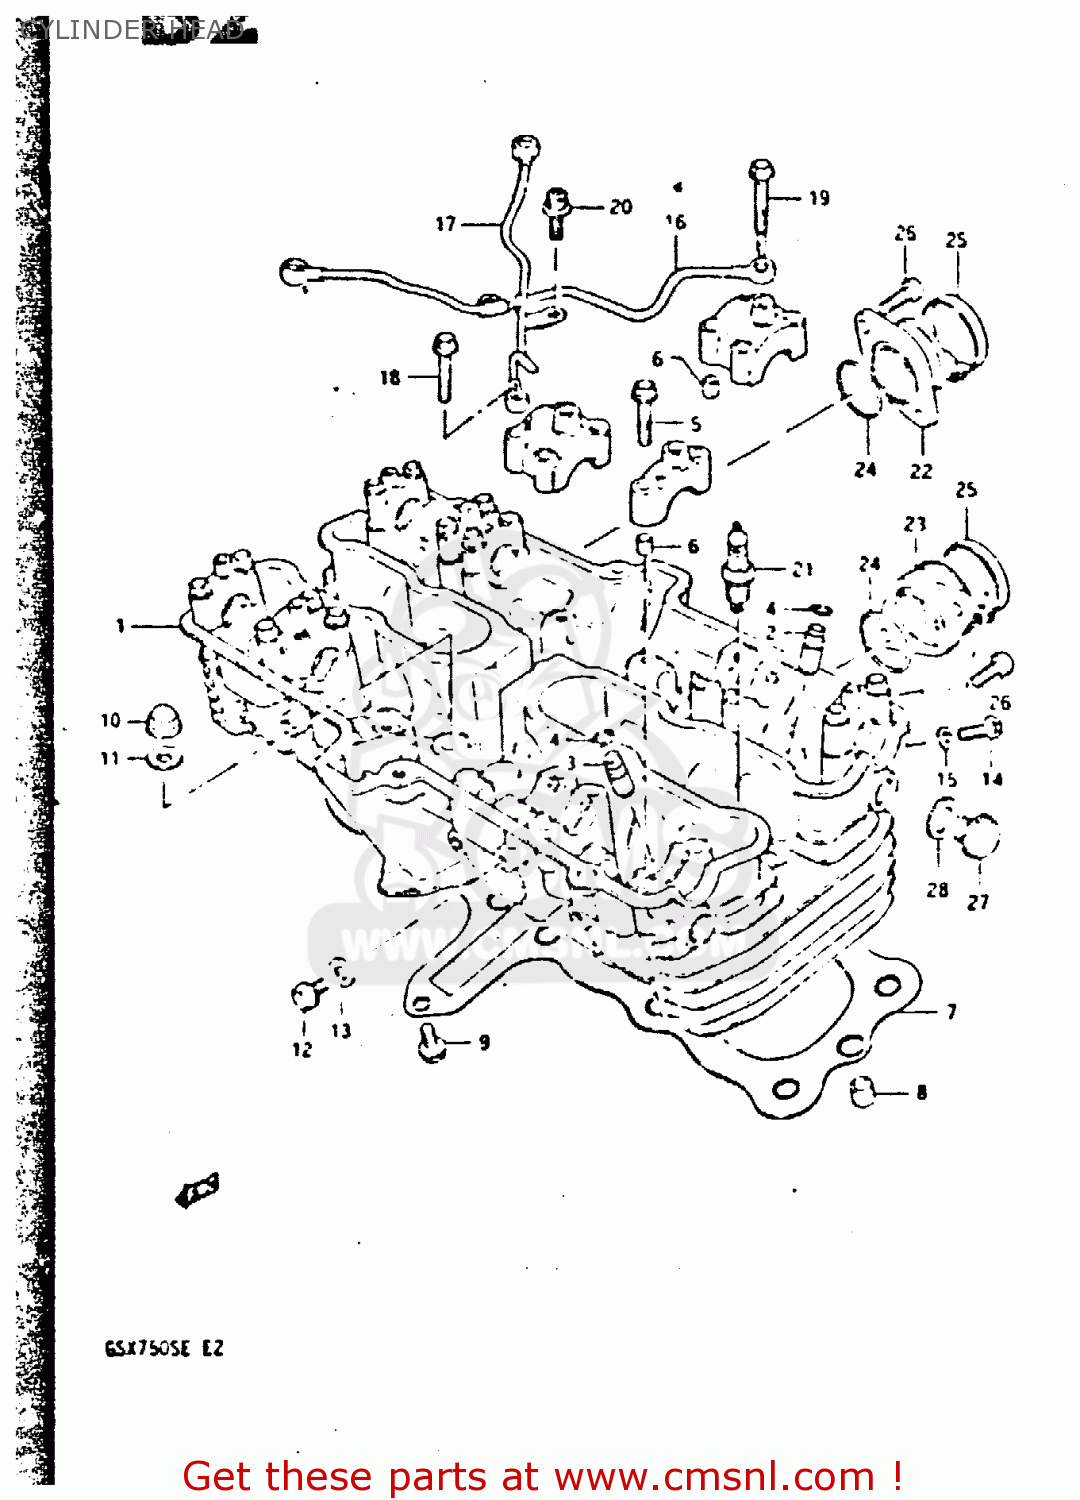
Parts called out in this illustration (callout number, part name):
1	CYLINDER HEAD SET
2	GUIDE,INTAKE VALVE
3	GUIDE,INTAKE VALVE
4	RING,SNAP
5	BOLT(6X39)
6	PIN(6.2X8X11)
7	GASKET,CYLINDER HEAD (NAS)
8	PIN
9	BOLT
10	NUT
11	GASKET(10.5X22X2) (NAS)
12	BOLT
13	GASKET(6.2X13X1.2) (NAS)
14	SCREW
15	GASKET(5.3X9.3X1.2) (NAS)
16	PIPE,OIL CYLINDER HEAD NO.1
17	PIPE,OIL CYLINDER HEAD
18	UNION
19	BOLT,UNION
20	BOLT
21	SPARK PLUG D8EA
22	PIPE,INTAKE
23	PIPE,INTAKE
24	O RING(D:2.4,ID:37.7)
25	CLAMP
26	SCREW
27	PLUG
28	GASKET(14X19.2X2) (NAS)
